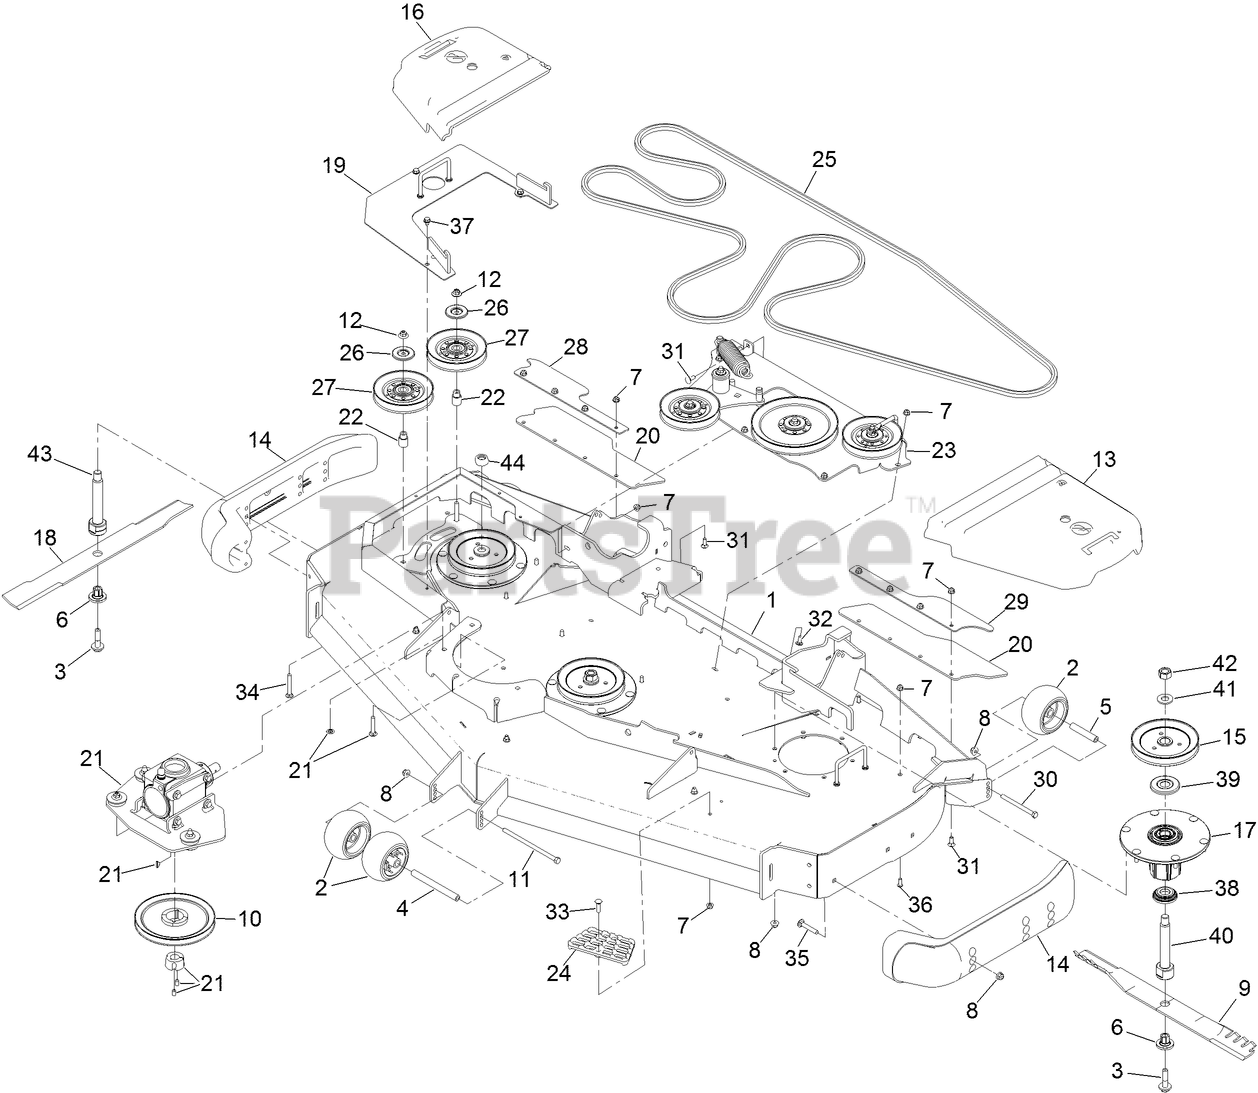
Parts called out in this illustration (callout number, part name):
1	DECK DECAL ASM
2	ROLLER-SCALP, ANTI
3	SCREW-SEMS
4	SPACER-WHEEL
5	TUBE-SPANNER
6	BUSHING-HEX
7	NUT-HF, NI
8	NUT-HF, NI
9	BLADE-24.50 ATOMIC
10	PULLEY
11	SCREW-HH
12	NUT-FLANGE, NI
13	COVER-BELT, LH
14	SKID-BUMPER, DECK
15	SHEAVE-BLADE DRIVE 6.50
16	COVER-BELT, RH
17	SPINDLE ASM
18	BLADE-24.50 CR LOW FLOW
19	COVER-REVERSE DRIVE
20	GUARD-TIRE
21	GEARBOX ASM
22	STANDOFF-IDLER
23	IDLER MOUNT ASM
24	STEP-DECK
25	BELT-BB
26	SHIELD-DUST
27	IDLER V
28	SUPPORT-FLAP, OUTER (RH)
29	SUPPORT-FLAP, OUTER (LH)
30	SCREW-HH
31	SCREW-CARR
32	SCREW-CARR
33	SCREW-CARR
34	SCREW-CARR
35	SCREW-CARR
36	SCREW-HSBH
37	SCREW
38	GUARD-BOTTOM
39	GUARD-BEARING, TOP
40	SHAFT-SPINDLE
41	WASHER
42	NUT-HEX
43	SHAFT-SPINDLE, INT. HEX LH THD
44	NUT-HEX,LH,LOCK
